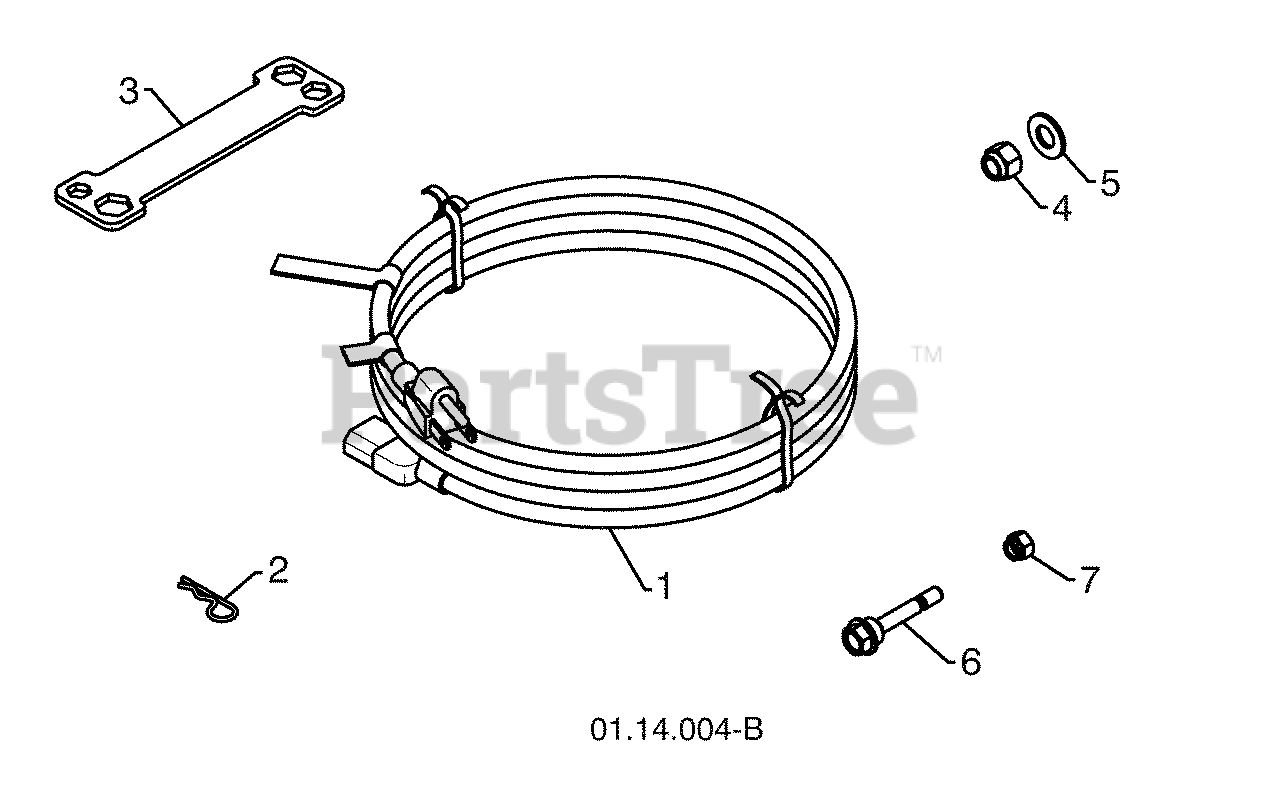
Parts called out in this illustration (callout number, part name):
1	POWER CORD
2	RETAINER PIN
4	LOCKNUT 3/8-16
5	WASHER 3/8
6	SHEAR BOLT 1/4-20 X 1-3/4
7	LOCKNUT 1/4-20
